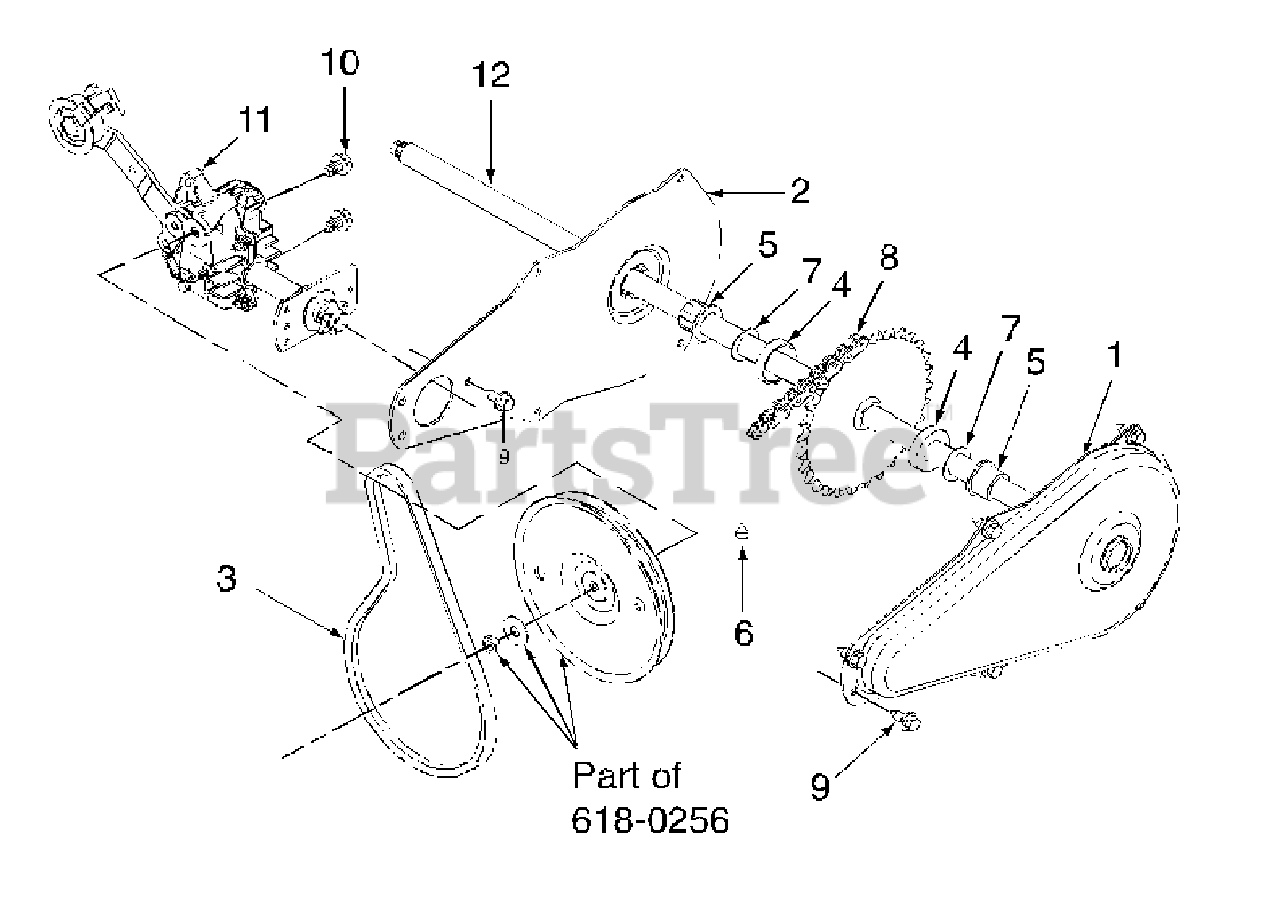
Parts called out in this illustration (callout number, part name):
1	Chain Case LH
2	Chain Case RH
3	V-Belt, 3/8 x 24.68
4	Spacer, .630 x 1.25 x .29
5	Bearing, Hex Flange, .631 ID
6	Grease, Benalene
7	Washer, Flat, 5/8 x 1.0
8	Chain, Endless, #41 x 50 Lnks
9	Screw, Hex Wash Hd, 1/4-14 x .625
10	Screw, Hex Wash Hd Tapp 5/16-18 x .50
11	Complete Transmission Ass'y
12	Shaft Assembly, Axle
